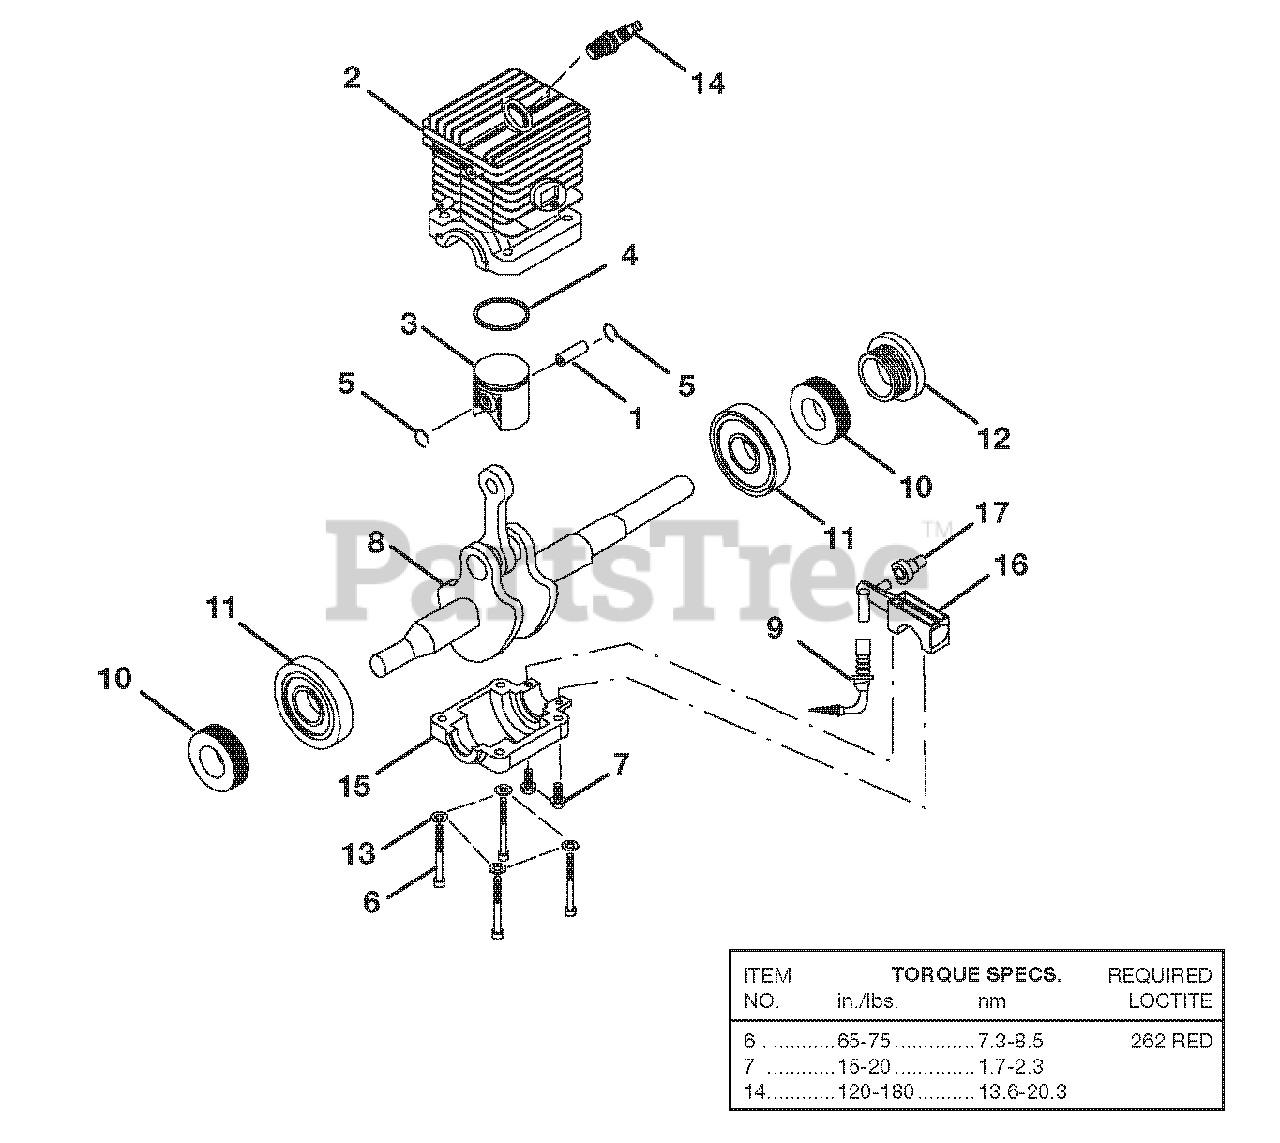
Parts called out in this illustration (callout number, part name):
1	PISTON PIN
2	CYLINDER MACH/PLATED
3	45CC PISTON (MACH)
4	PISTON RING
5	RETAINING RING
6	SCREW TORX PLUS CAP-SOCKET HD
7	SCREW, (8/32 X 5/8 in. PAN HD TORX)
8	45CC SINTERED METAL CRANKSHAFT ASSEMBLY
9	OIL INTAKE TUBE W/FILTER
10	SHAFT SEAL
11	BEARING CASE ASSEMBLY
12	LEFT HAND WORM
13	FLAT WASHER
14	SPARK PLUG
15	CRANKCASE (45CC) CS
16	OIL PUMP ASSEMBLY
17	GROMMET, OIL OUTLET
